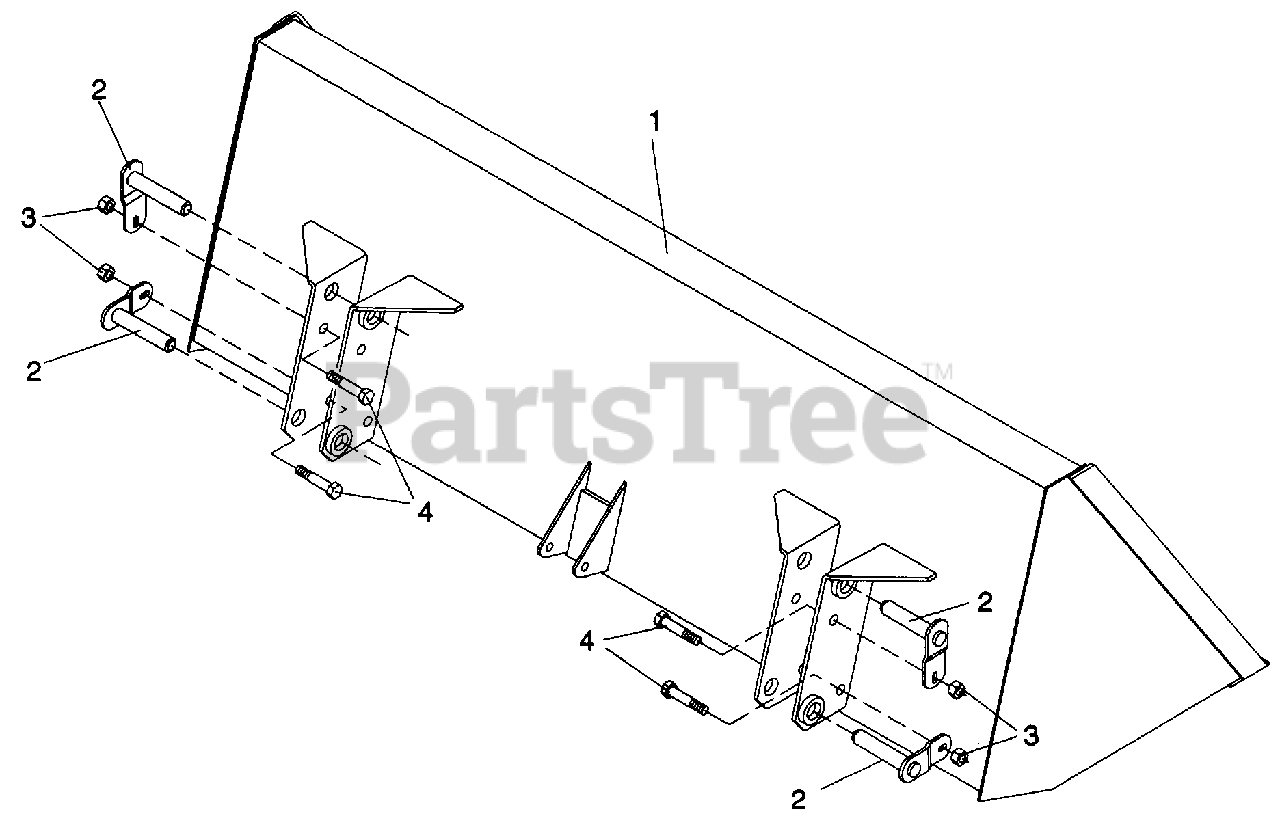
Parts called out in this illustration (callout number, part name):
1	48" Bucket
2	Pin weldment
3	3/8 NC Locknut
4	3/8 NC x 1 Capscrew
